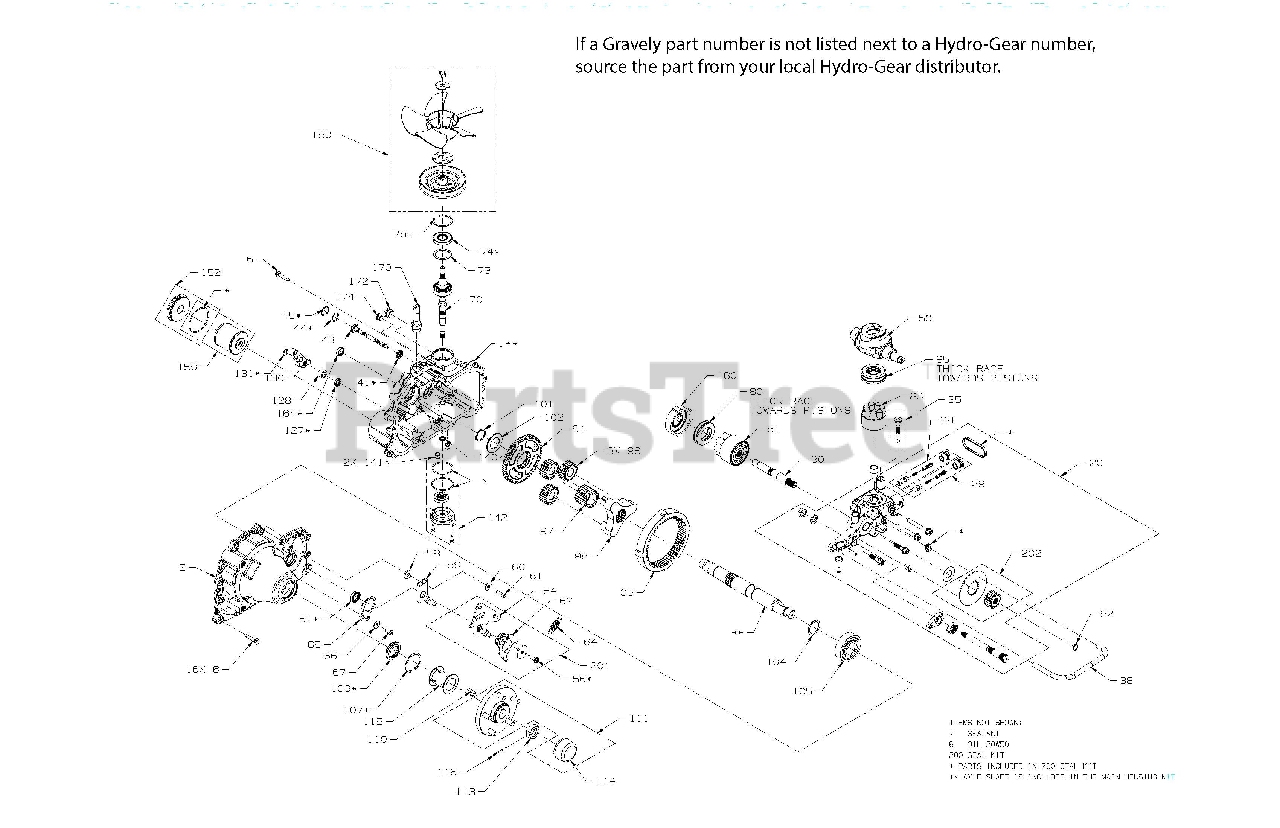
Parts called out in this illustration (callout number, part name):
1	KIT, HOUSING, MAIN, RH
2	KIT, HOUSING, SIDE, RH
7	SEALANT TUBE 10.1OZ.
20	CENTER SECTION KIT R(03935200)
28	HG SHOCK VALVE KIT
29	HG SHOCK VALVE KIT
35	HG CHARGE RELIEF VALVE KIT
38	TUBE, FILTER, RH
41	SEAL, LIP 12 X 24 X 5 TC
43	ASSEMBLY, ACTUATOR BYPASS
44	SPRING, WAVE
50	SWASHPLATE, 16CC, MACHINED
54	ARM, CONTROL, RH
56	TWHCS 5/16-24 X 1.00
58	SPACER
59	ARM, NEUTRAL RIGHT
60	WASHER
61	SHCS 5/16-24X1 PATCH
62	ASSEMBLY, RTN, UNI-DIRECTIONAL
64	RTN SPRING HG 51605
65	PLATE, STOP, RH
66	WASHER
70	INPUT SHAFT HG 71941
73	SPACER
74	SEAL, LIP 24 X 52 X 7 TC
75	RING, RETAINING, INTERNAL
80	BRG, THRUST 42 X 68 X 16, PLASTIC CAGE
81	KIT, MOTOR BLOCK
86	KIT, BLOCK, 16CC CYLINDER
90	SHAFT, MOTOR
92	RING, RET 62 EXT
98	CARRIER
100	BALL, .75
102	SPACER, THRUST, AXLE
105	BEARING,BALL 35 X 80 X 21 6307
106	HG SEAL LIP 1.375X2.062X.250
107	RING, RETAINING
110	KEY, WOODRUFF 5/16 X 1
111	HG 5 BOLT HUB KIT
113	HG HEX NUT 1-20 SLOTED
114	CAP, AXLE
116	PIN, COTTER 9/64 X 2 EXTENDED
127	SEAL- LIP .562X.875X.187
130	BRAKE ARM HG 53018
131	RING, RETAINING
140	SEAL, .50 X .69 X .09 VC
141	TUBE, PUSH O-RING
142	CHARGE COVER KIT
150	FILTER,HYD OIL W/ORING ZT-54OO
152	HG FILTER PLUG KIT
160	PLATE, MOTOR, SWASH
164	SEAL, PLUG
170	FITTING, 7/8-14 SAE, .625 BEADED
172	PLUG 7/8-14, METAL
174	PLUG, 9/16-18, METAL
180	PULLEY/FAN KIT HG 71906
200	SEAL KIT HG 71945
201	KIT, RTN, RH, UNI-DIRECTIONAL
202	KIT, BRAKE ROTOR, GEAR
